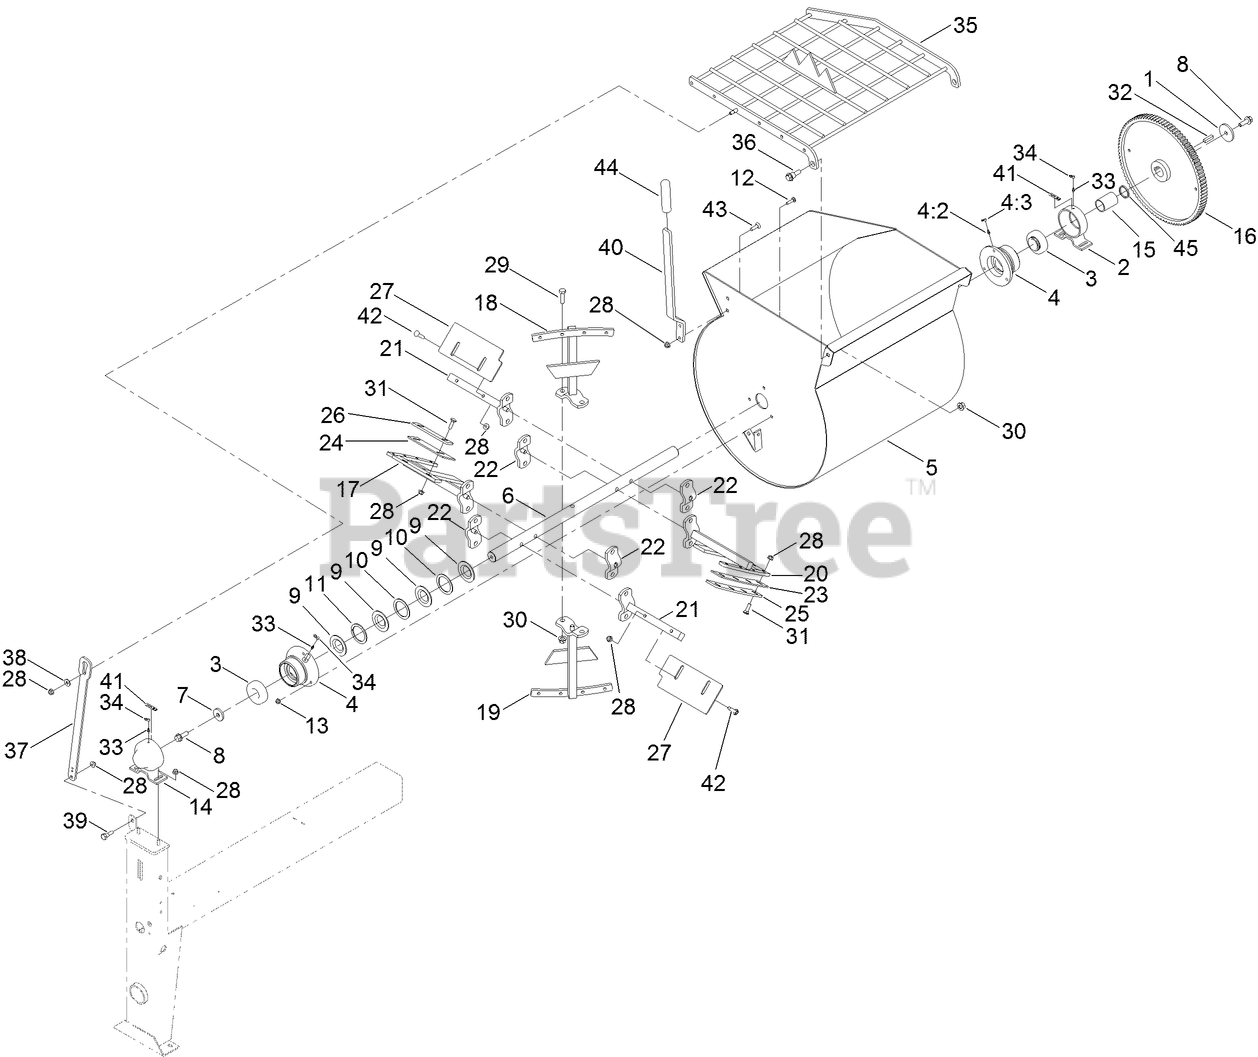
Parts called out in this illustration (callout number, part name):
1	WASHER-PLAIN
2	TRUNNION
3	BEARING-BALL
4	KIT-HOUSING, BEARING
4:2	FITTING-GREASE
4:3	CAP-PLUG
6	SHAFT-PADDLE
7	WASHER-FLAT
8	SCREW-HHF
9	SEAL-DRUM
10	WASHER-FLAT
11	WASHER-SPLIT
12	SCREW-CARR
13	NUT-HF, NI
14	TRUNNION-CAPPED
15	SPACER-TUBULAR
16	GEAR-94 TEETH
17	PADDLE-LEADING
18	PADDLE-MID
19	PADDLE-MID
20	PADDLE-TRAILING
21	PADDLE-PUSHER
23	PADDLE-RUBBER, TOP
24	PADDLE-RUBBER, MIXER END
25	BAR-BACKER, TOP
26	BAR-BACKER, END
27	BAR-BACKER, PUSHER END
28	NUT-HF, NI
29	SCREW-HH
30	NUT-LOCK
31	BOLT-CARR
32	KEY-SQUARE
33	FITTING-GREASE
34	CAP-PLUG
35	GUARD-DRUM, 85MM
36	SCREW-SHOULDER, HHF
37	ARM-LIFT, GRATE
38	WASHER-HARDENED
39	BOLT-SHOULDER
40	HANDLE-DUMP
41	DECAL-GREASE
42	SCREW-CARR
43	SCREW-CARR
44	GRIP-FOAM
45	SPACER-SHAFT, DRUM
